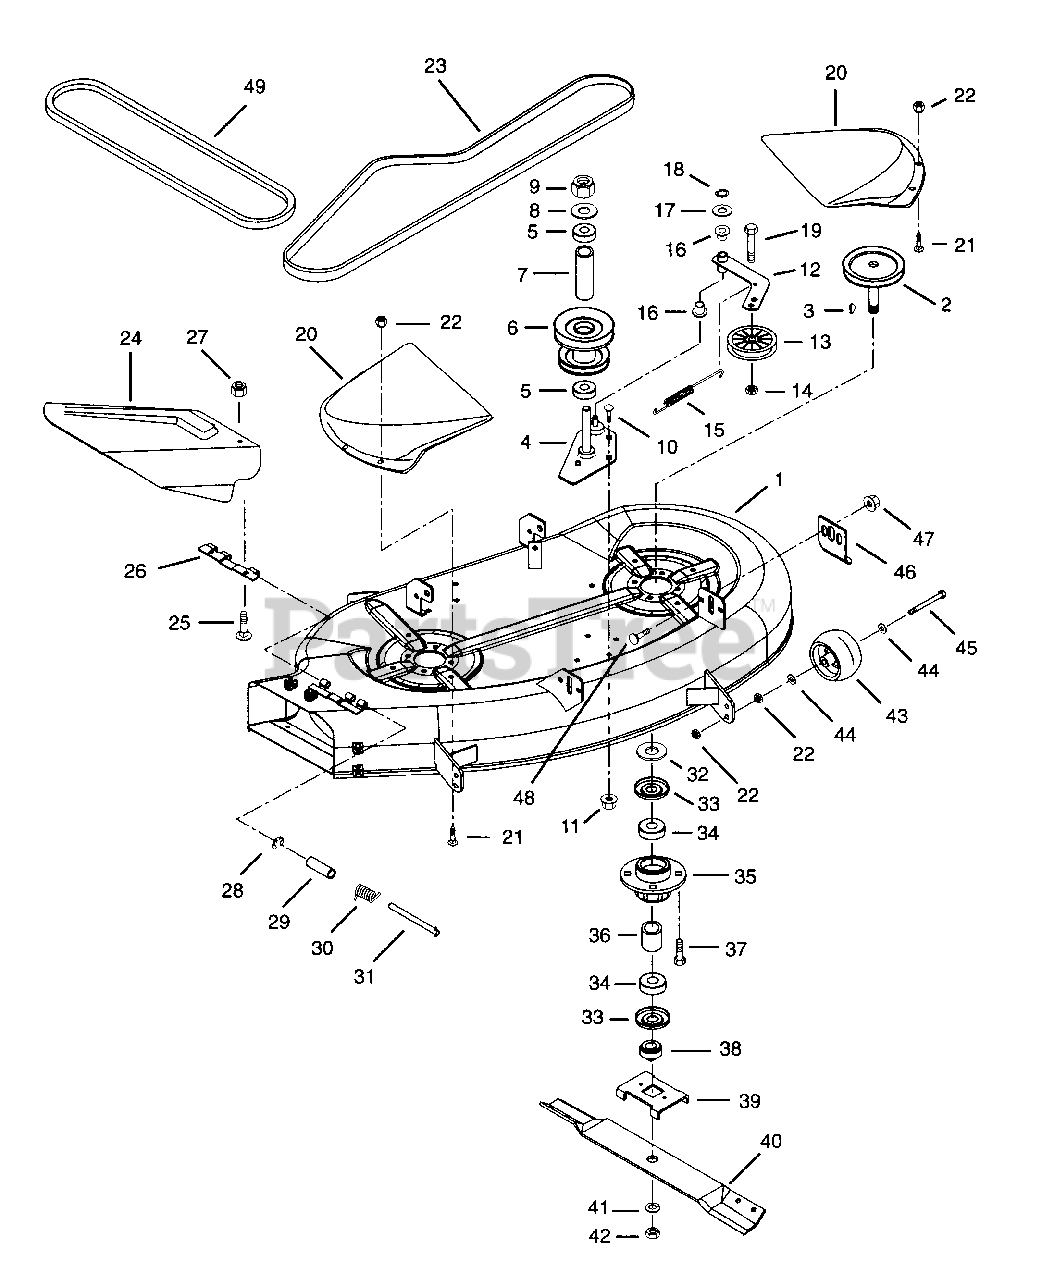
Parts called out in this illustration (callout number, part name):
1	40" MOWER DECK W/DECALS
1	40" MOWER DECK ASSY COMPLETE
2	L. SPINDLE SHEAVE
2	R. SPINDLE SHEAVE
3	KEY-WDRF .188X.625X.31 SAE9MOD
4	MOUNT PLATE 40"
5	BRG-BALL .625X1.375X.44
6	JACKSHAFT PULLEY
7	SPACER .640X.880X2.545
8	WSHR-FL-STL .640X1.005X.062 PL
9	NUT-LK-NYL.625-18 PL
10	BLT-RDHDSQNK .312-18X.62SHTPL
11	NUT-FLG. .312-18 PL
12	IDLER ASSY
13	IDLER-FLAT 3.00X.38
14	NUT-LK TOP .375-16 GR C YWZC
15	SG-TENS .113X.812X7.00
16	BSHG-FLG .500X.625X.187X.750FD
17	WSHR-FL-STL .505X.880X.072 PL
18	RG-RTNG-EXT .500X.042 (E)
19	BLT-HEX .38-16X1.50 PL GR5
21	BLT-RDHDSQNK .38-16X1.0 PL
22	NUT-LK-CTR .375-16 GR A PL
23	V-BELT, HA-WRAPPED
24	40IN. CHUTE DEFLECTOR
25	BLT-RDHDSQNK .25-20X.50 SHT PL
26	HINGE PLATE
27	NUT-LK-FLG .250-20 PL
28	RG-RTNG-EXT .312X.025
29	BSHG-SLV .334 X .502 X 1.437
30	SG-TORS .095X.50X 1.0
32	WSHR-FL-STL .755X1.250X.125
33	BEARING SLINGER
34	BRG-BALL .750X1.781X.61
35	SPINDLE HOUSING
36	SPACER .753X1.000X1.140
37	BLT-HEX .38-16X1.00 PL GR5
38	RETAINER HUB
39	BLADE TRAY 48
41	WSHR-LK .750X.188 MED PL
42	NUT-JAM .75-10 PL
44	WSHR-FL-STL .38X.875X.083 PL
45	BLT-HEX .38-16X3.50 PL GR5
46	MOWER ADJUSTMENT TAB
47	NUT-FLG. .312-18 PL
48	BLT-RDHDSQNK.31-18X.75GR5SHTPL
49	V-BELT, 4L-RAW EDGE
